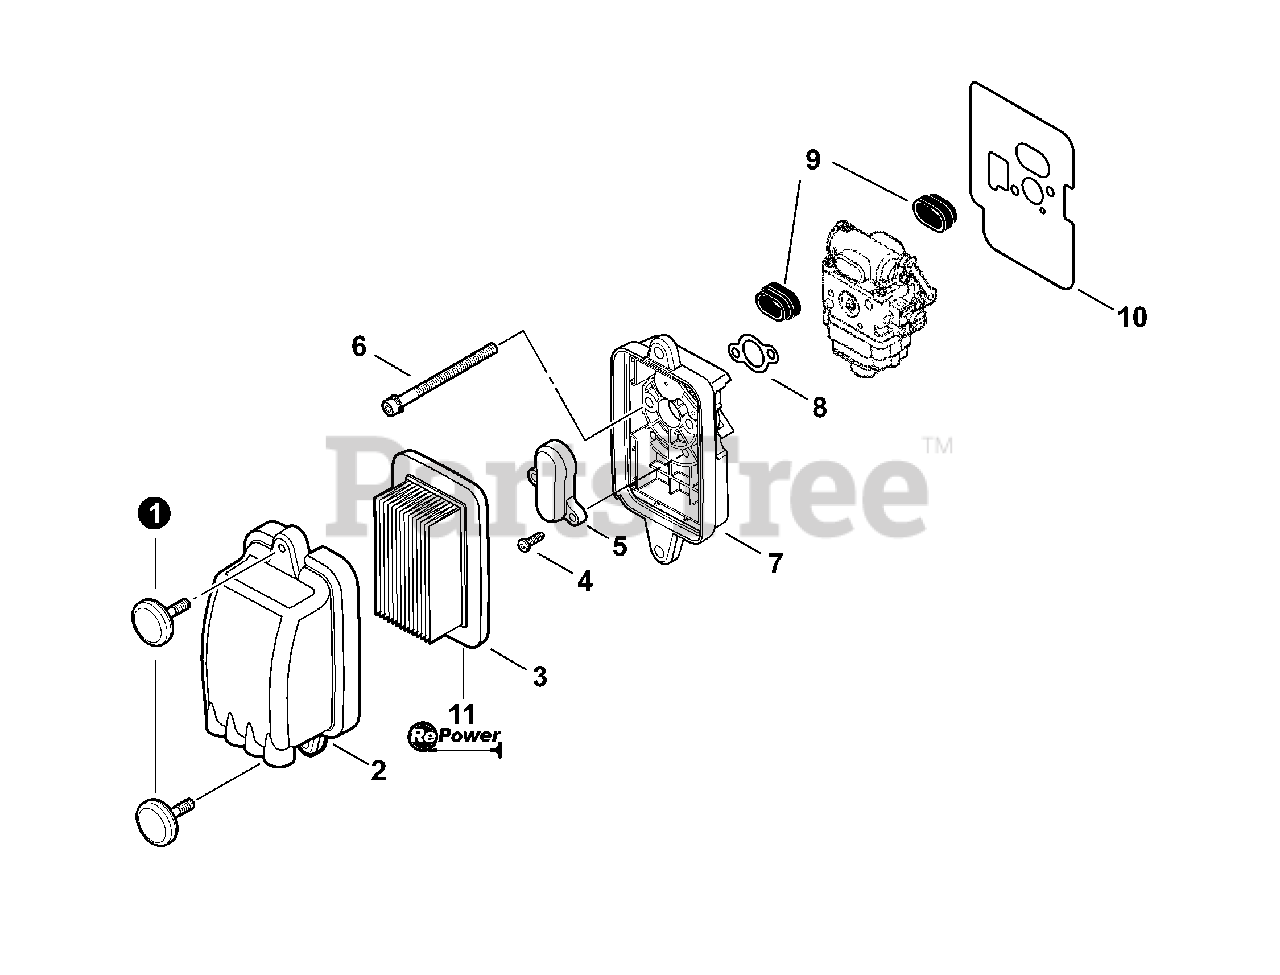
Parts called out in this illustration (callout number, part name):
1	THUMBSCREW
2	COVER, AIR FILTER
3	FILTER, AIR
4	SCREW TAPPING 4×14
5	PLATE, PREVENT
6	SCREW 5×65
7	CASE, AIR FILTER
8	GASKET, INTAKE
9	CONNECTOR
10	GASKET, INTAKE
11	TUNE-UP KIT - REPOWER
